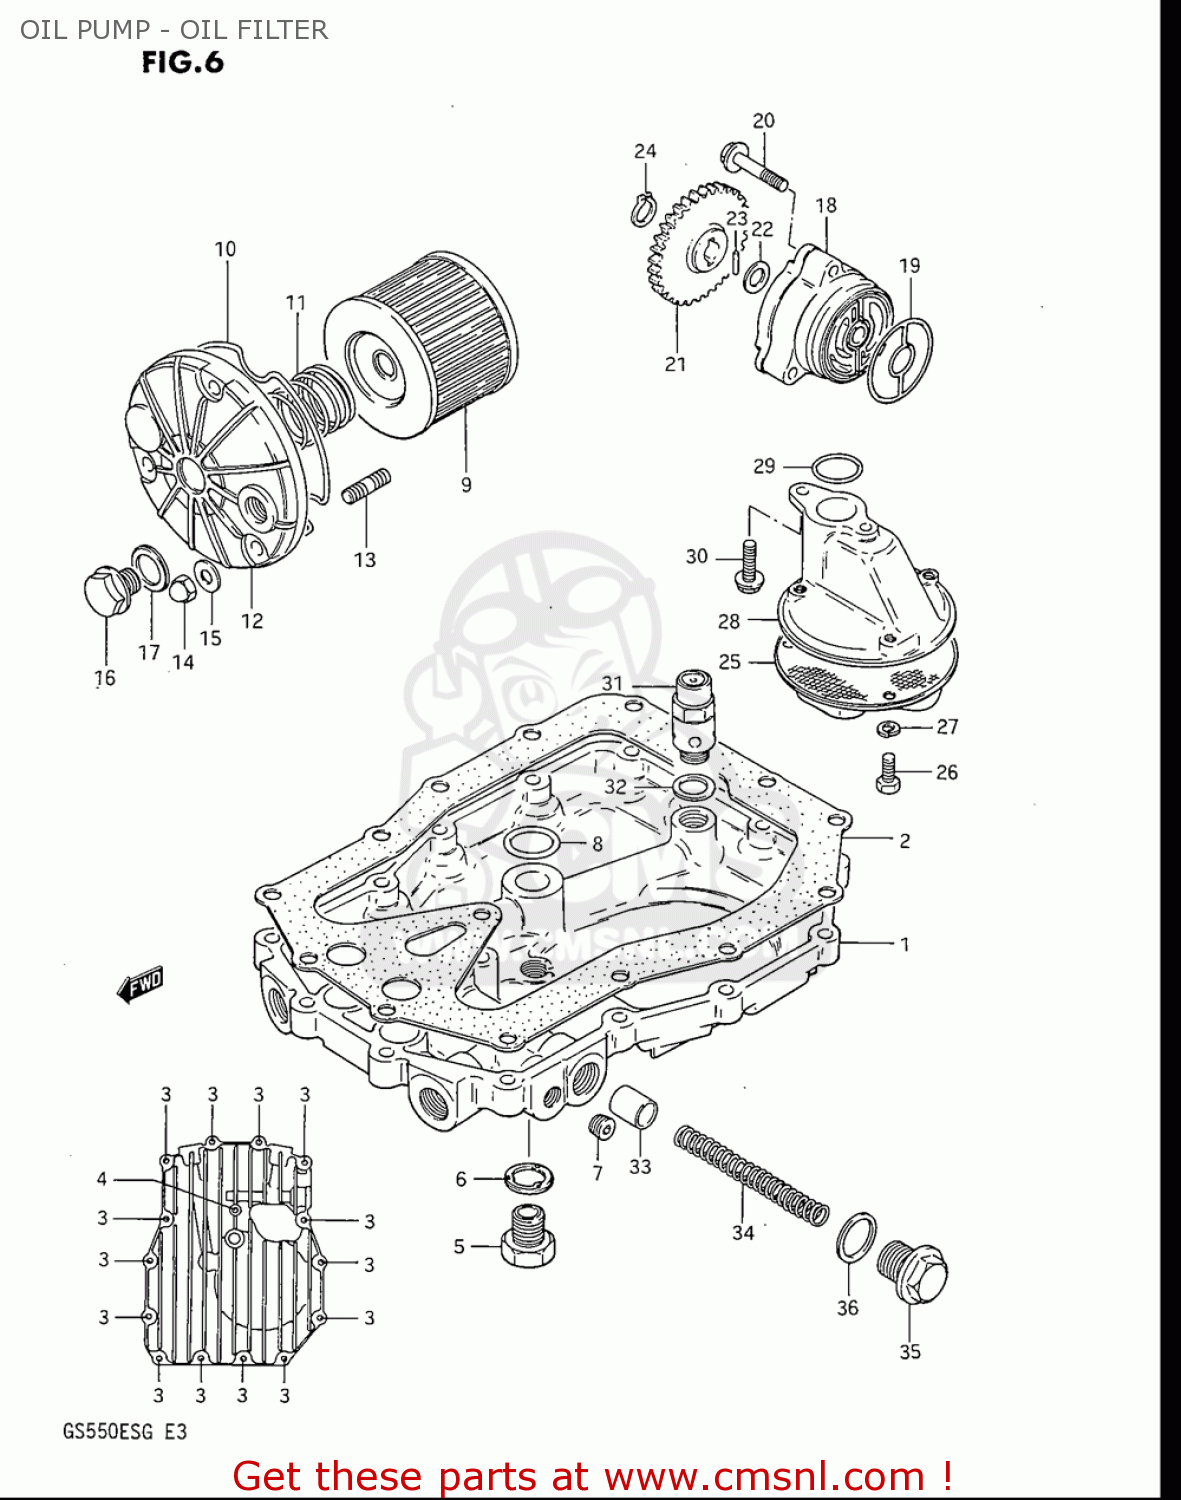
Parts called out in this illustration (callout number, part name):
1	PAN,OIL
2	GASKET,OIL PAN (NAS)
3	BOLT
4	BOLT
5	PLUG(MAGNETO)
6	GASKET(14X19.2X2) (NAS)
7	PLUG OIL GALLER
8	O RING(D:3.2,ID:17.8)
9	FILTER ASSY,ENGINE OIL
10	O RING,OIL FILTER CHAMBER CAP
11	SPRING
12	CAP,ENGINE OIL FILTER
13	BOLT,STUD
14	NUT
15	WASHER
16	PLUG(14X12)
17	GASKET(14X19.2X2) (NAS)
19	O RING,OIL PUMP
20	BOLT(6X32)
22	SHIM
23	PIN(4X15.8)
24	CIRCLIP
25	STRAINER,ENGINE OIL
26	BOLT
27	WASHER,LOCK
29	O RING(D:3.2,ID:17.8)
30	BOLT
31	REGULATOR,ENGINE OIL(6.5K)
32	WASHER
33	PLUNGER,OIL CONTROLL
35	PLUG
36	O RING(D:2.4,ID:16.8)
